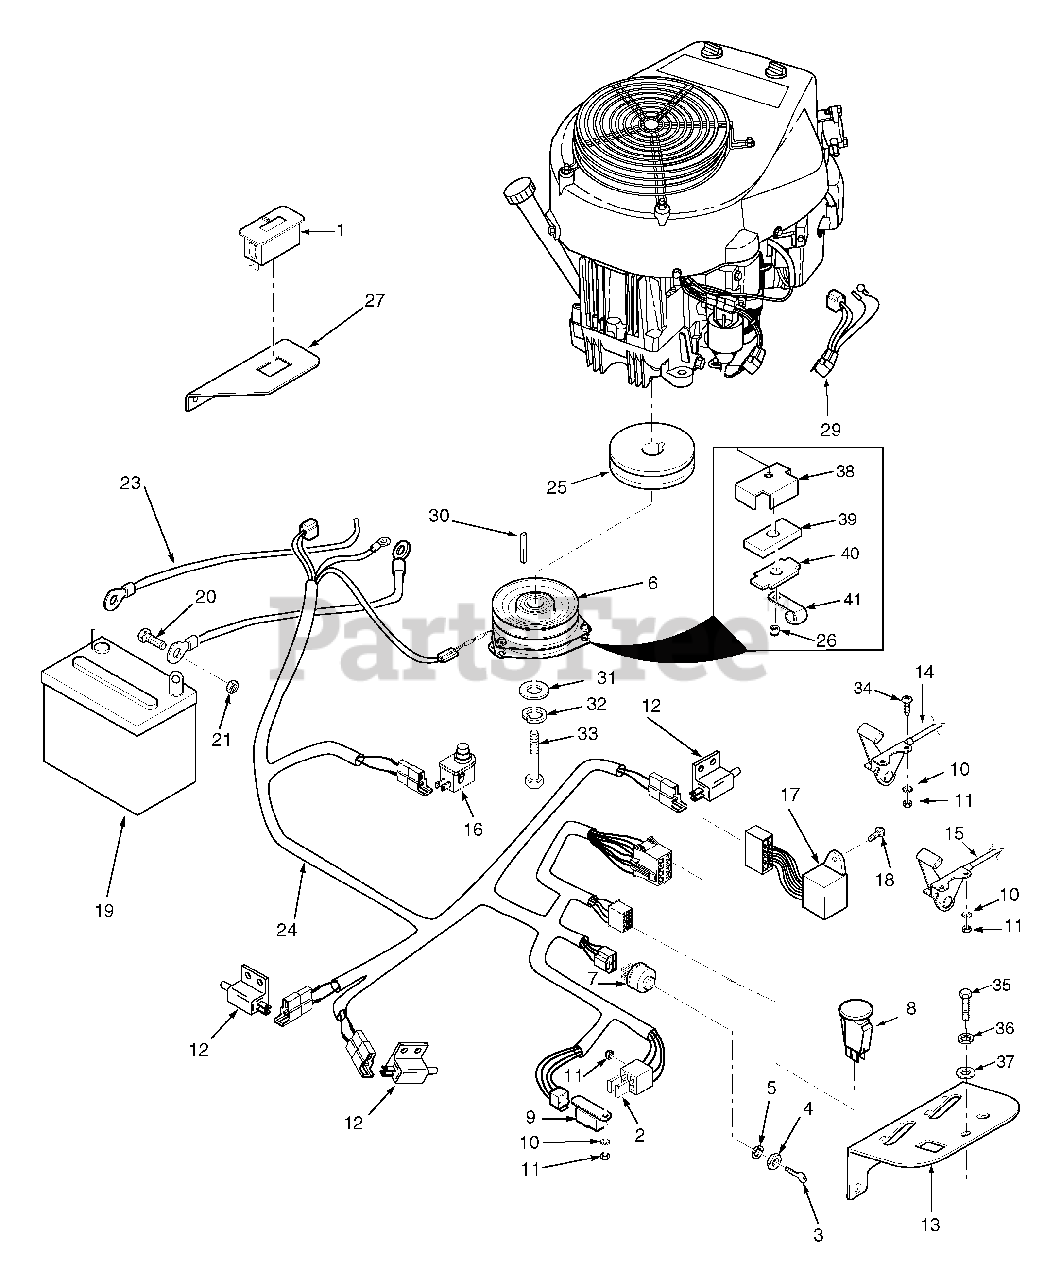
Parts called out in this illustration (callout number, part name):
1	Hourmeter
2	Fuse, 20 amp
3	Key, Ignition
4	Nut, Hex 5/8-32
5	Lockwasher, 5/8" Internal
6	Electric PTO Clutch GT3.5
7	Switch, Ignition
8	Switch, PTO
9	Relay
10	Lock Washer, #10 External Tooth
11	Nut, Hex #10-32
12	Switch, N/O
13	Panel, Instrument
14	Choke & Throttle Control - Kawasaki
15	Throttle Control - Kohler
16	Switch, Seat
17	Module, Interlock
18	Screw, #10-32 x .5" Phillips Head
19	Battery
20	Bolt, Hex Head 1/4-20 x .5"
21	Nut, Hex 1/4-20
22	Cable, Battery Black (negative)
23	Cable, Battery Red (positive)
24	Wiring Harness, Main
25	Pulley, 5.45 OD x 1.125 Bore
26	Nut, Elastic Stop 5/16-18 Key
27	Mounting Bracket, Hour Meter
28	Screw, #10-32 x 1.5" Phillips Head
29	Adaptor, Wiring Harness (Kawasaki only)
30	Key, 1/4 x 1/4 x 3-1/4"
31	Flatwasher, 7/16-.469 x 1-3/4" x 1/4"
32	Lockwasher, 7/16"
33	Bolt, Hex Head 7/16-20 x 2-1/2" UNF
34	Screw, #10-32 x 3/4"
35	Bolt, Hex Head 5/16-18 x 3/4"
36	Lockwasher, 5/16
37	Flatwasher, 5/16-.375 x .875 x .083
38	Backing Plate
39	Rubber Pad, Clutch Stop
40	Plate, Backing
